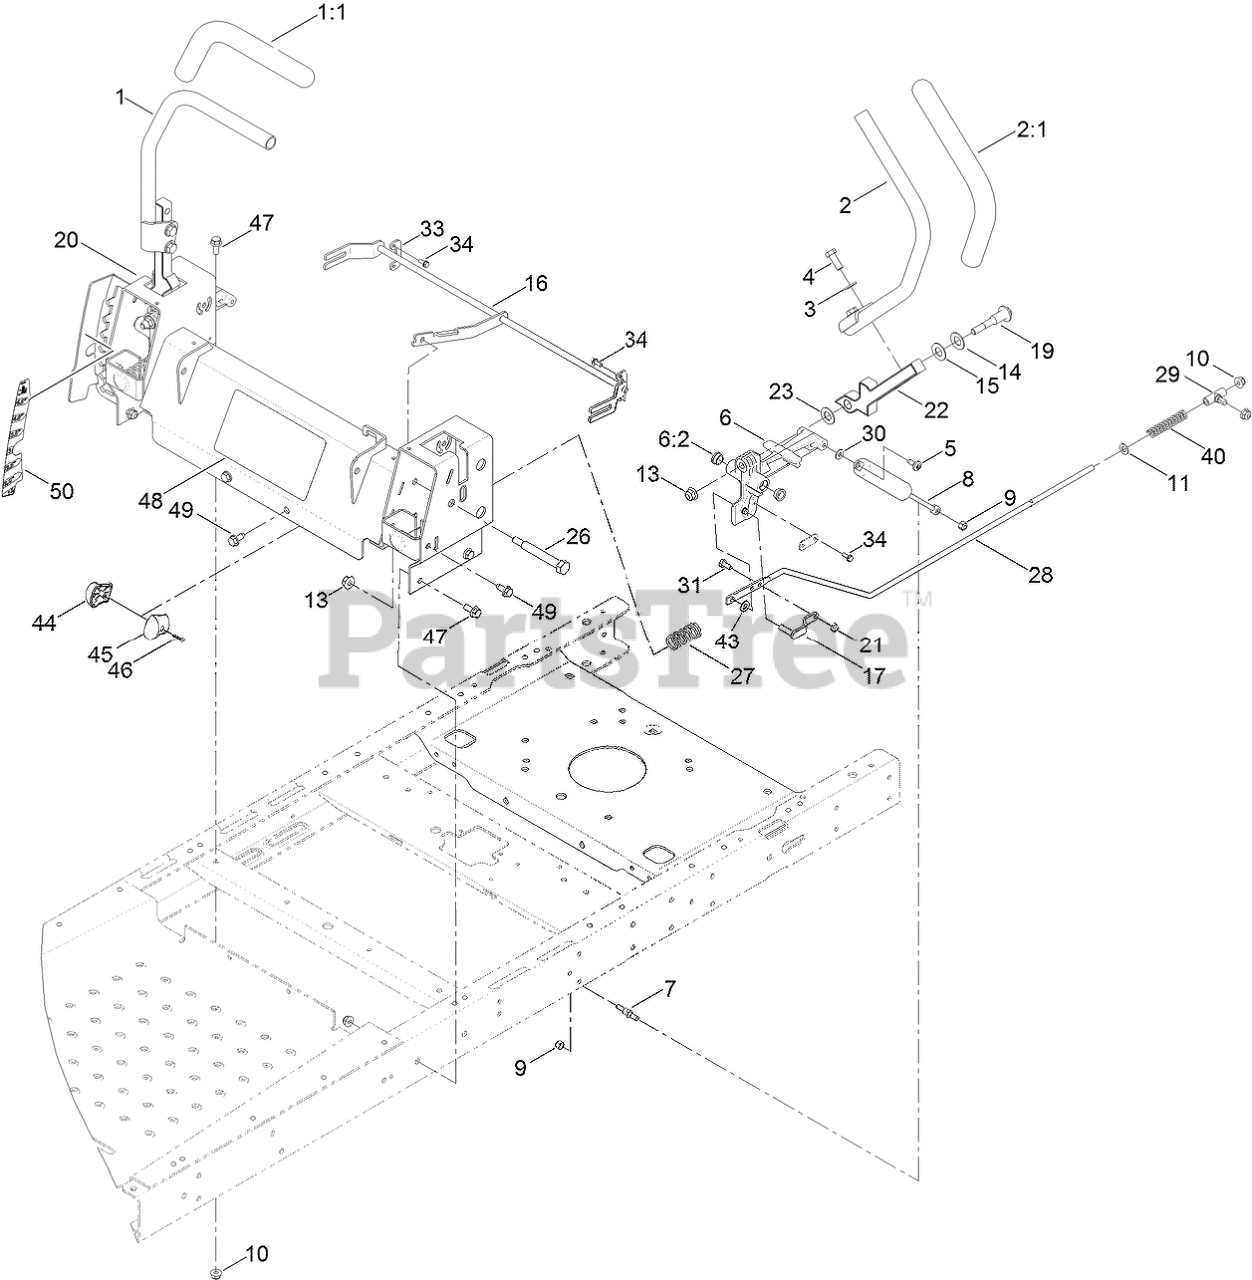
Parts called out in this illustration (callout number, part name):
1	HANDLE-CONTROL, RH
2	HANDLE-CONTROL, LH
3	WASHER-FLAT
4	SCREW-HH
5	SCREW-SHOULDER
6	ACTUATOR ARM ASM
6:2	BUSHING-FLANGE
7	STUD-DAMPER
8	DAMPER
9	NUT-LOCK, NI
10	NUT-HF, NI
11	WASHER-PLAIN
13	NUT-HF, NI
14	WASHER-BELLEVILLE
15	WASHER
16	SPEED CONTROL ASM
17	PIN-ROD, HYDRO
19	BOLT-PIVOT
20	CONTROL BOX ASM
21	NUT-LOCK, NI
22	LEVER-CONTROL
23	WASHER-NYLON
26	BOLT-PIVOT
27	SPRING-RETURN
28	ROD-HYDRO
29	MOUNT-ROD, HYDRO
30	WASHER
31	SCREW-HH
33	RETAINER
34	SCREW-TAPTITE
40	SPRING-RETURN, NEUTRAL
43	SPACER-NYLON
44	KNOB-RH
45	KNOB-LH
46	SCREW-PPH
47	SCREW-HHF
48	DECAL-CONTROL, SPEED
49	SCREW-HWHTF
50	DECAL-HOC
